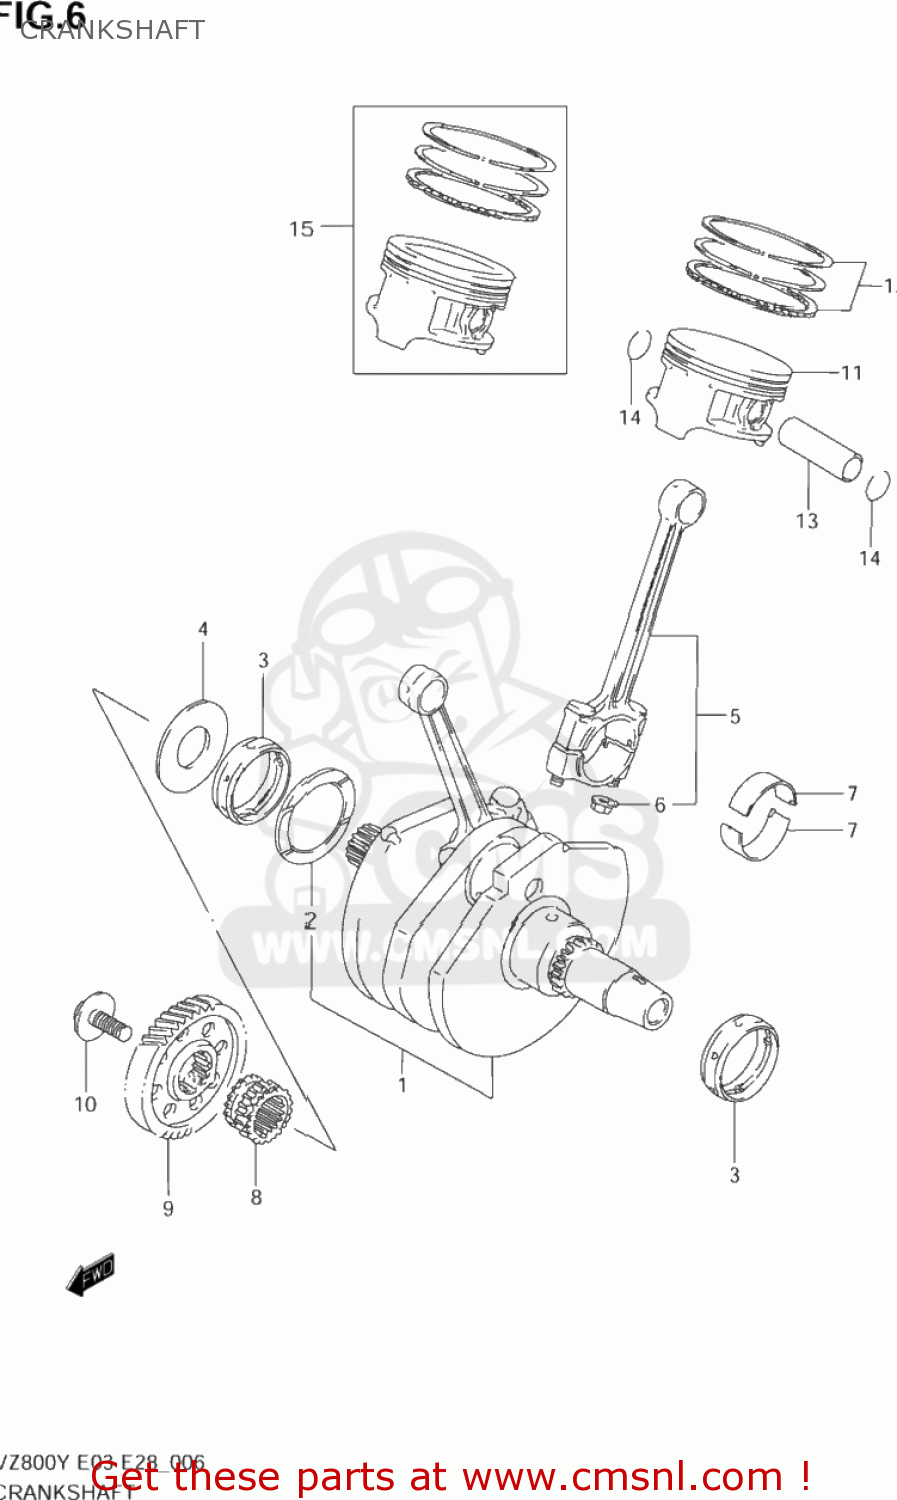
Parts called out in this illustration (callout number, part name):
1	CRANKSHAFT SET
2	WASHER(48.1X64X1.94)
3	METAL,CRANKSHAFT
4	WASHER,CRANK THRUST
5	CONNECTING ROD ASSY
6	NUT
7	BEARING,CRANK PIN
8	SPROCKET,CAM CHAIN DRIVE,R
9	GEAR,PRIMARY DRIVE
10	BOLT(12X28)
11	PISTON
12	RING SET,PISTON
13	PIN,PISTON
14	CIRCLIP,PISTON PIN
15	PISTON SET(OS:0.5)
